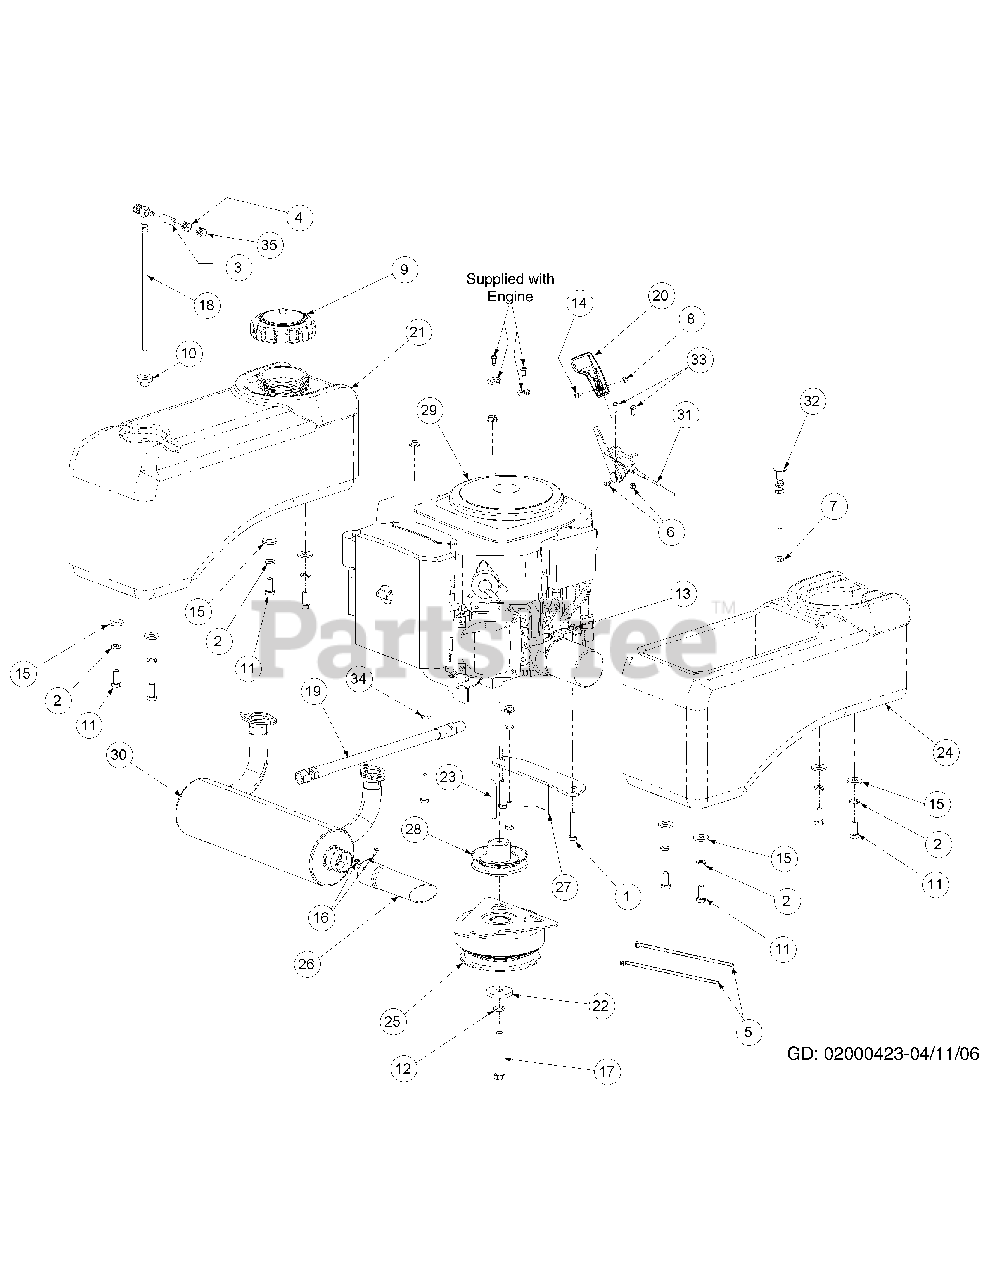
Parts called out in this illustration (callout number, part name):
1	Hex Head Cap Screw, 5/16-18 x 1-3/4
2	Lock Washer, 3/8 Zinc
3	Hose, 1/4" Fuel Line
4	Clamp, Union
5	Cable Tie, 3/16 x .05 x 7.4
6	Lock Nut, Nylon Insert, 10-32
7	Hex Jam Nut, 3/8-24
8	Nut, w/ Star Washer
9	Fuel Cap
10	Fuel Tank Groment
11	Hex Cap Screw, 3/8-16 x .88
12	Lock Washer, 7/16
13	Lock Nut, Hex Flange, 5/16-18
14	Machine Screw, 8-32 x .375
15	Idler Washer
16	Screw, 8-32 x .375, Hex Washer
17	Hex Cap Screw, 7/16-20 x 3.0
18	Fuel Pickup Fitting
19	Oil Drain Extension Hose
20	Throttle Control Knob
21	Fuel Tank
22	Flat Washer, 7/16 ID x 1.75 OD x .250
23	Key, 1/4 x 1/4 x 2.75
24	Utility Bin
25	Ogura DX11 Electric Clutch
26	Exhaust Pipe
27	Clutch Retainer Assembly
28	Electric PTO Engine Pulley
29	23HP Kohler Engine
30	Kohler Muffler
31	Throttle Control Cable
32	Choke Cable
33	Screw, #10-32 x 0.500
34	Washer, 3/8 x .738 x .063
35	Hose Clamp, 1/4-5/8, SS
